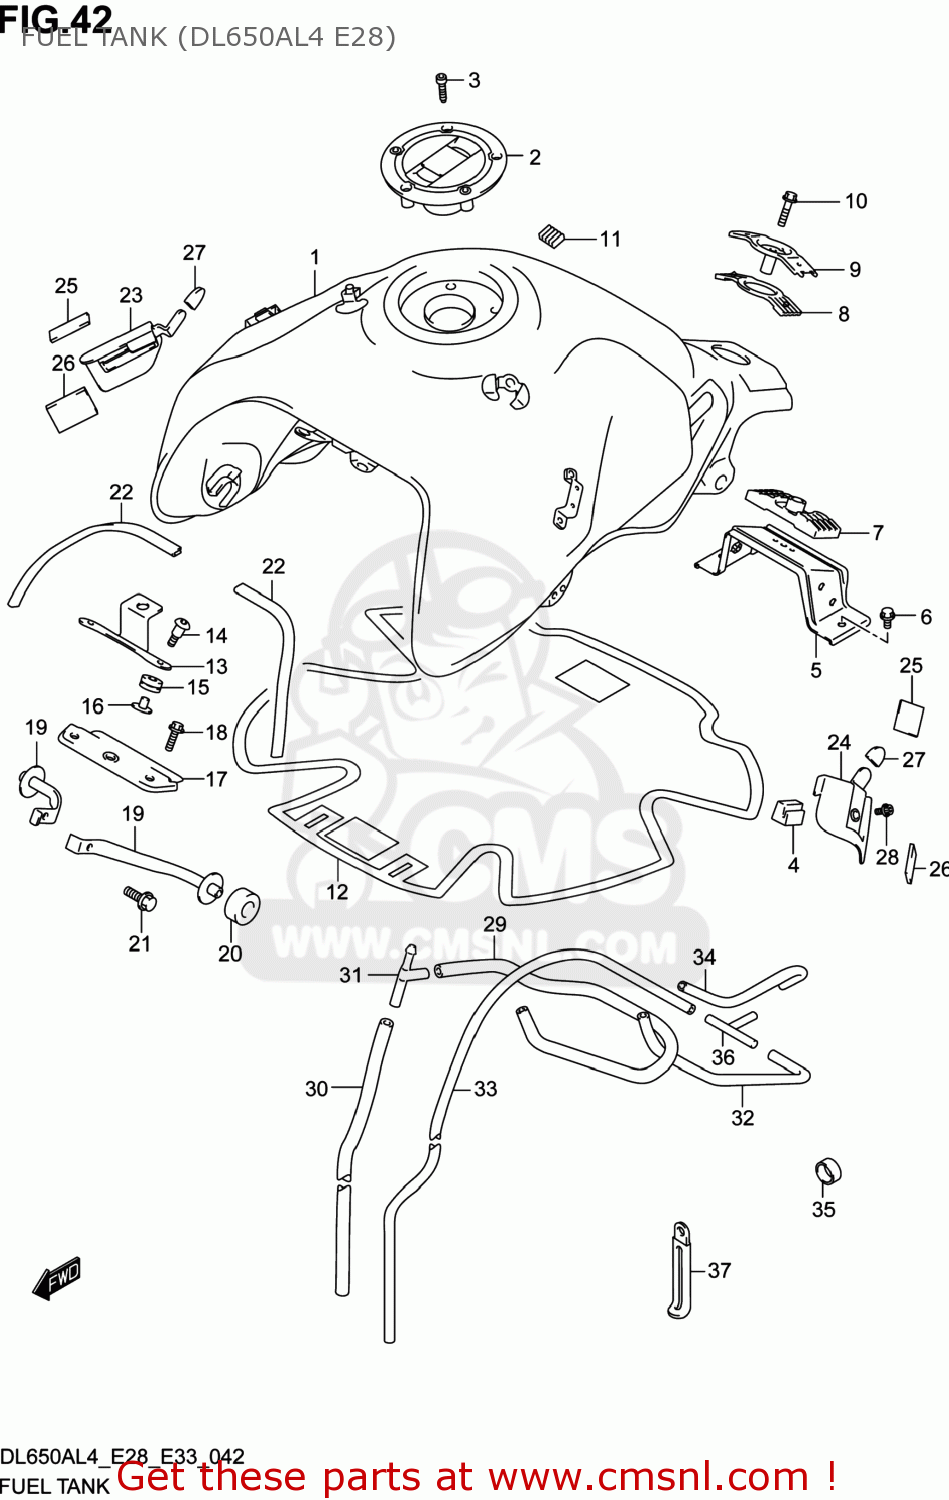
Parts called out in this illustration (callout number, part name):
1	TANK ASSY,FUEL(BLACK)
2	CAP SET,FUEL TANK
3	BOLT,FUEL TANK FILLER CAP
4	CUSHION,FUEL TANK SIDE
5	BRACKET,FUEL TANK RR
6	BOLT
7	CUSHION,FUEL TANK RR LWR
8	CUSHION,FUEL TANK RR UPR
9	BRACKET,FUEL TANK RR UP
10	BOLT
11	FASTENER
12	SHIELD,FUEL TANK CTR
13	BRACKET,FR COVER
14	SCREW(6X25)
15	CUSHION,FUEL TANK FR
16	SPACER,FUEL TANK FR
17	BRACKET,FUEL TANK FR
18	BOLT
19	BRACKET,FR SIDE
20	CUSHION,FR SIDE BRKT
21	BOLT
22	MOLDING,FUEL TANK
23	BRACKET,FUEL TANK COVER,R
24	BRACKET,FUEL TANK COVER,L
25	FASTENER
26	CUSHION,TANK SIDE COVER
27	CUSHION
28	BOLT
29	HOSE,FUEL TANK DRAIN NO.1
30	HOSE,FUEL TANK DRAIN NO.2
31	3 WAY
32	HOSE,FUEL TANK BREATHER NO.1
33	HOSE(5X8.2X2000)
34	HOSE(5X8.2X600)
35	HOSE(12X16X600)
36	3 WAY
37	CLAMP(L:80)
